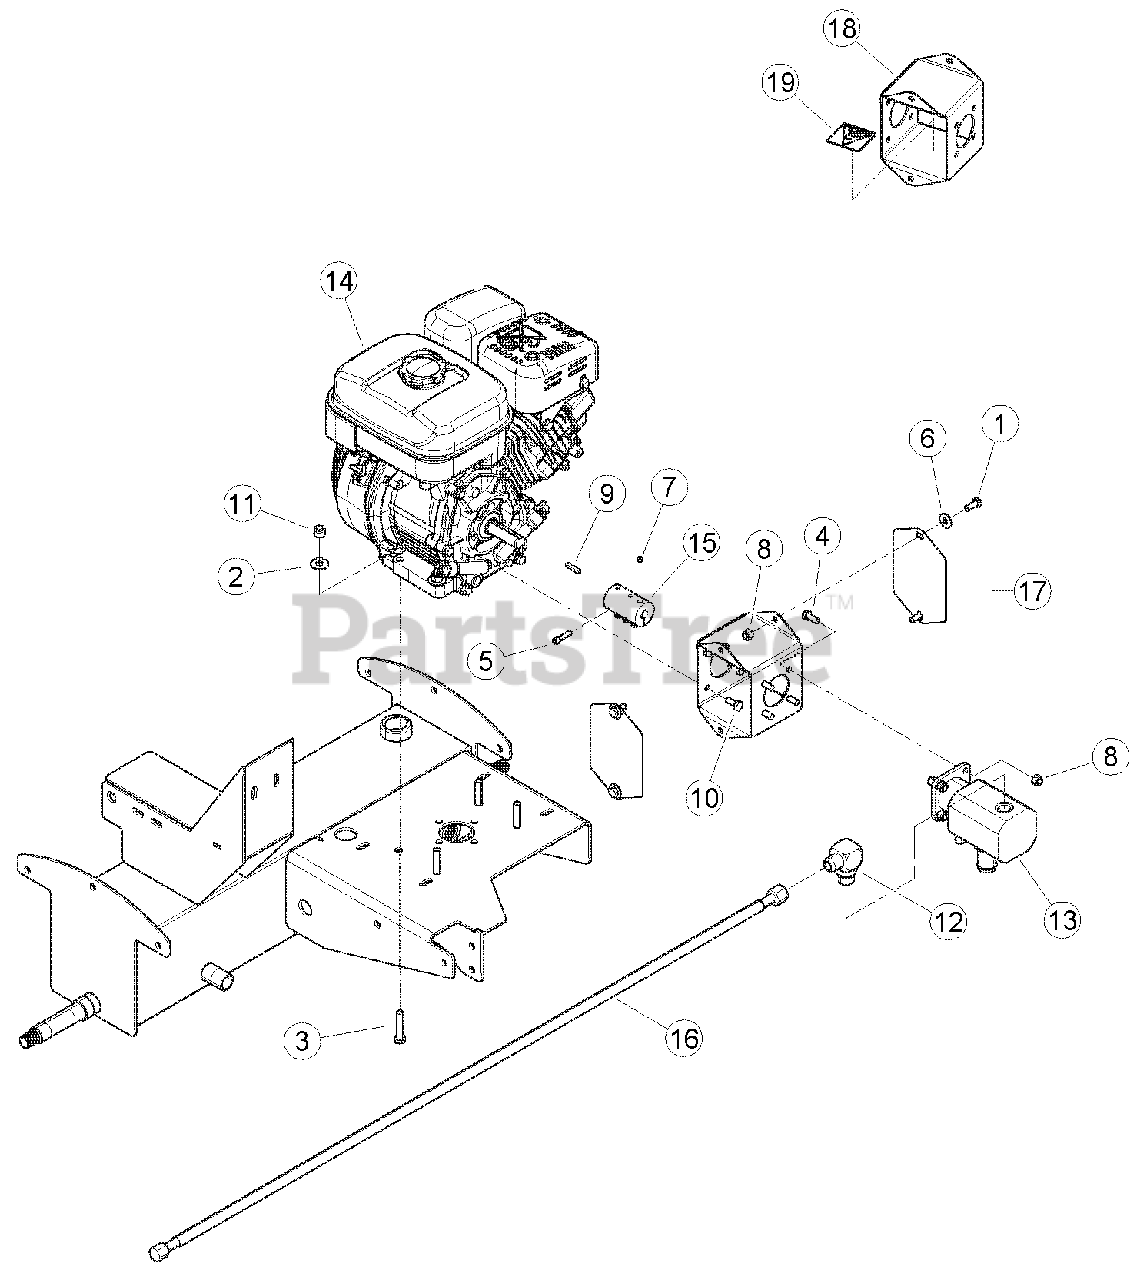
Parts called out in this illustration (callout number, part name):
1	BOLT, 5/16 X 3/4 HEX HD GR5 ZP
2	WASHER, 3/8 FLAT ZP
3	BOLT, 3/8 X 1-3/4 HEX HD GR5 ZP
4	BOLT, 5/16 X 1 HEX HD GR5 NC ZP
5	BOLT, 1/4 X 1 SOC HD CAP SCRW (WAS 15242, REMOVED)
7	SCREW, 1/4-20 X 1/4 KNR CUP SKT SET (WAS 15332, REMOVED)
8	NUT, 5/16 NE NYLOCK ZP
9	KEY, 3/16 SQUARE X 1 LONG
10	BOLT, 5/16-24 X 3/4 HEX HD GR5 ZP
11	NUT, 3/8 NE NYLOCK ZP
12	ADAPTER, -10 MORING / -10 MJIC 90 DEG.
14	ENGINE, SUBARU SP210 (FOR SERVICE CONSULT ENGINE OWNER'S MANUAL OR YOUR NEAREST AUTHORIZED SUBARU INDUSTRIAL ENGINE DEALER.)
15	COUPLER, SPLIT 3/4" TO 1/2" SHAFT (PN 31963-00, REMOVED)
16	HOSE, .50 X 50 -10FJICSW/-10FJICSW
17	PLATE, PUMP MOUNT COVER
18	WELDMENT, PUMP MOUNT, SERVICE PART
19	DECAL, SHIELD DANGER ISO
